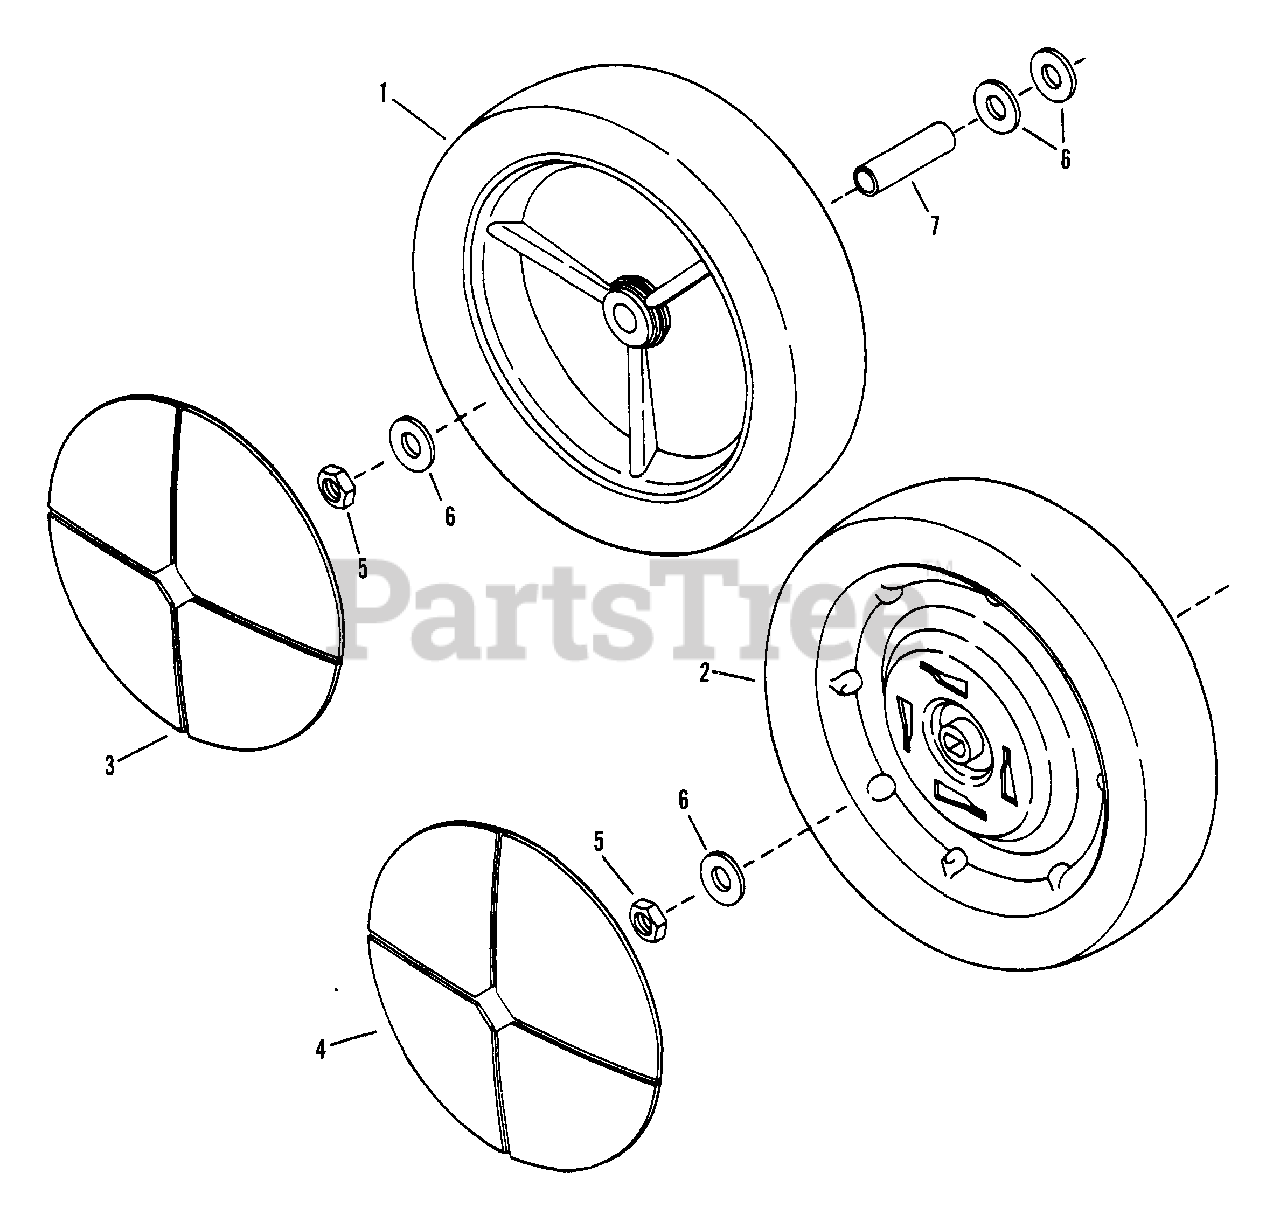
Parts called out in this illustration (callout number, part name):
1	WHEEL, 9 x 2.00 Plastic Rim
2	WHEEL, 9 x 2.00 Steel Rim
3	COVER, Wheel
4	COVER, Wheel
5	NUT, 5/16-18 Hex Center Lock
6	WASHER, 7/16 Flat
7	BUSHING, Axle
